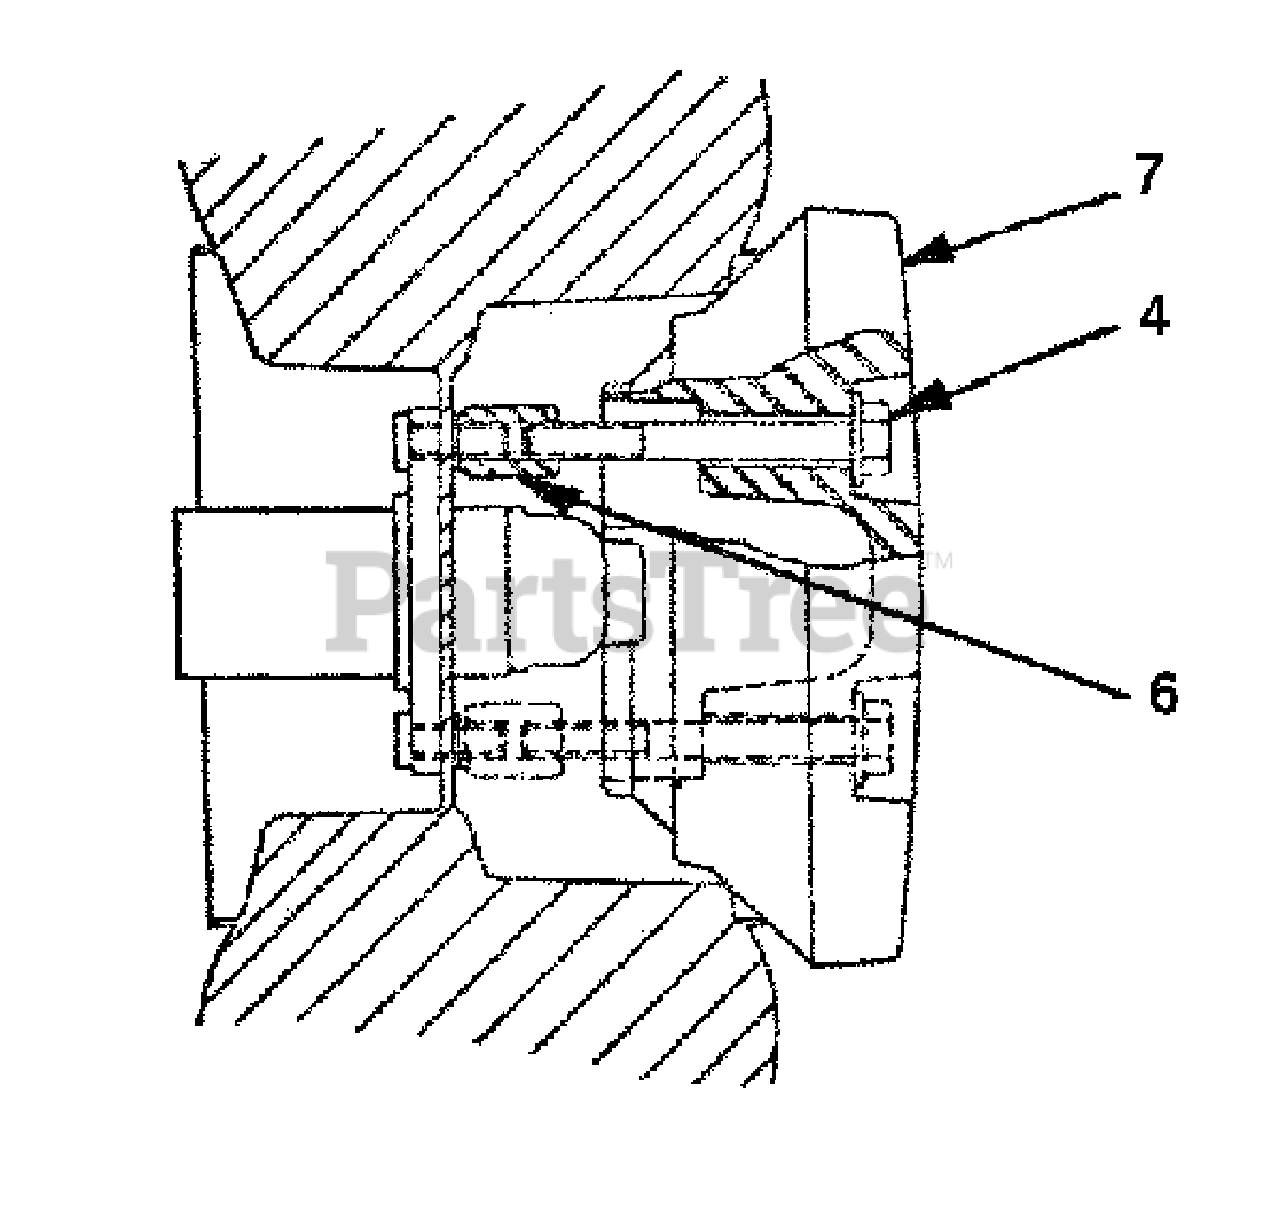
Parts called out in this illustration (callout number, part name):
4	Hex Screw 1/2-20 x 4-1/2"
6	Lug Nut (Long) 1/2-20
7	Wheel Weight
